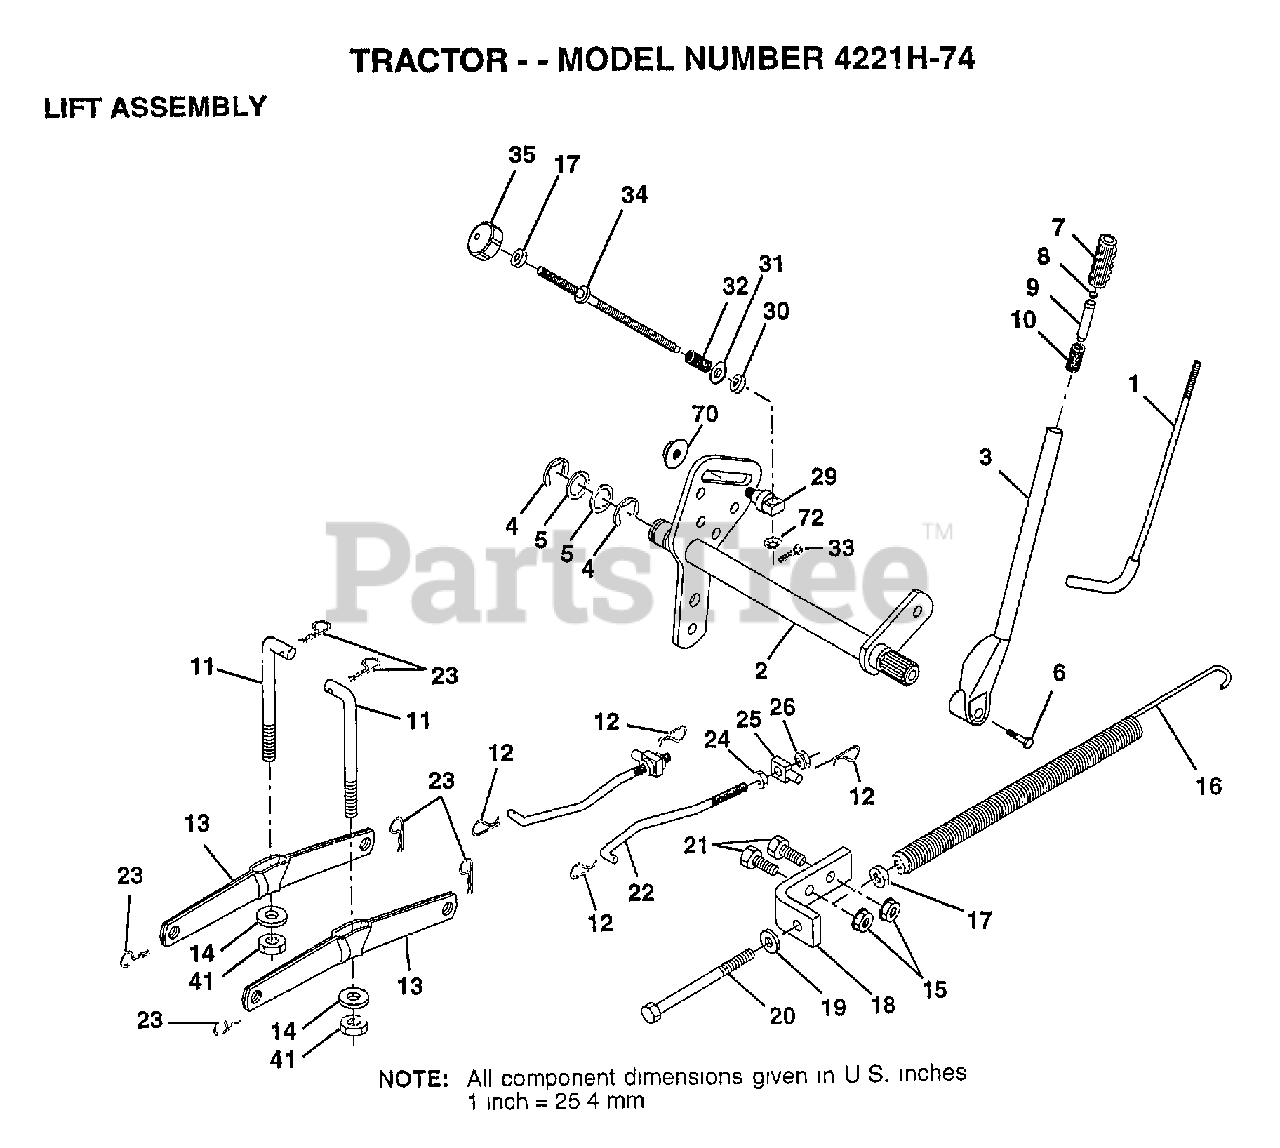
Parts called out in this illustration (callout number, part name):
1	LEVER ROD LT
2	SHAFT AMS LIFT
4	E-RING
5	WASHER
6	"BOLT,HEX"
7	GRIP
10	SPRING T
11	LINK.LIFT.MWR.VGT
12	RETAINER.SPRING
13	ARM SUSP REAR
14	BEARING PVT LH
17	NUT
18	BRACKET SPRING AS
19	WASHER
20	BOLT-ADJ SPRING T
21	BOLT
22	LINK.FRONT
24	NUT
25	TRUNION
26	NUT.LK.W/WSH.1/2.
29	TRUNNION
30	NUT T
31	WASHER
32	SPRING.COMP.INF.H
34	ROD.ADJ.LIFT
35	KNOB INF 3/8-16
41	NUT.CROWNLOCK.3/8
70	NUT.HXFLG.LOCK.
72	NUT PUSH M
